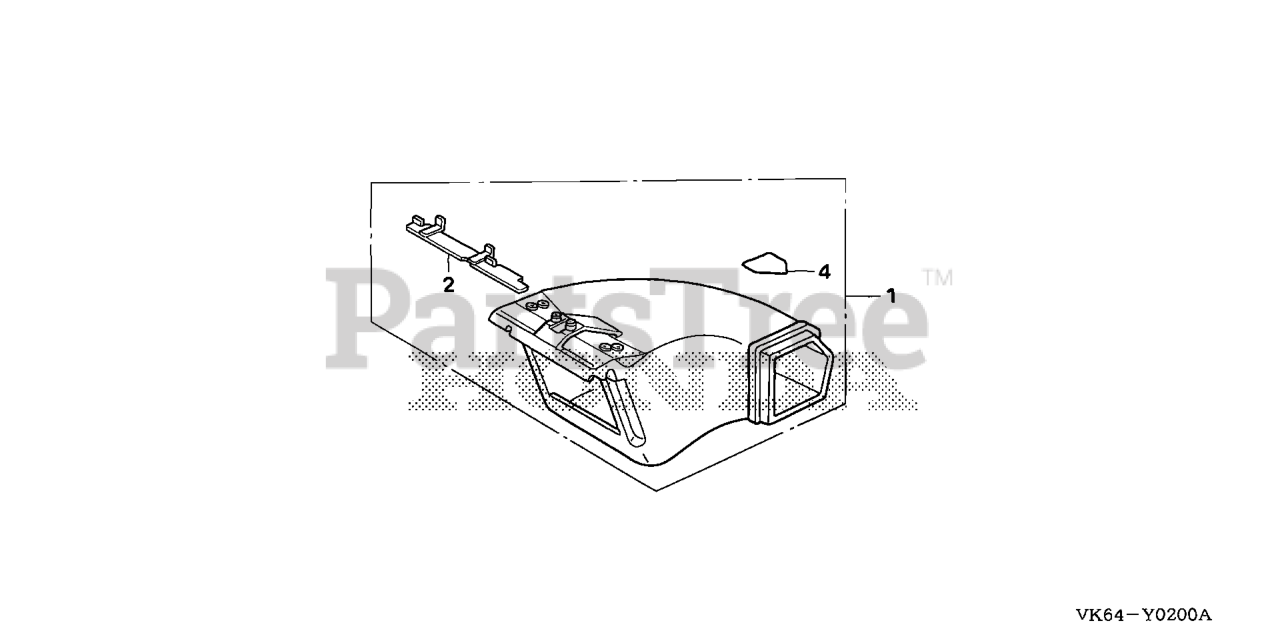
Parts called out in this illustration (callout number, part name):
1	CHUTE KIT, SIDE DISCHARGE
2	BRACKET, MOUNTING
4	LABEL C, HOUSING CAUTION
